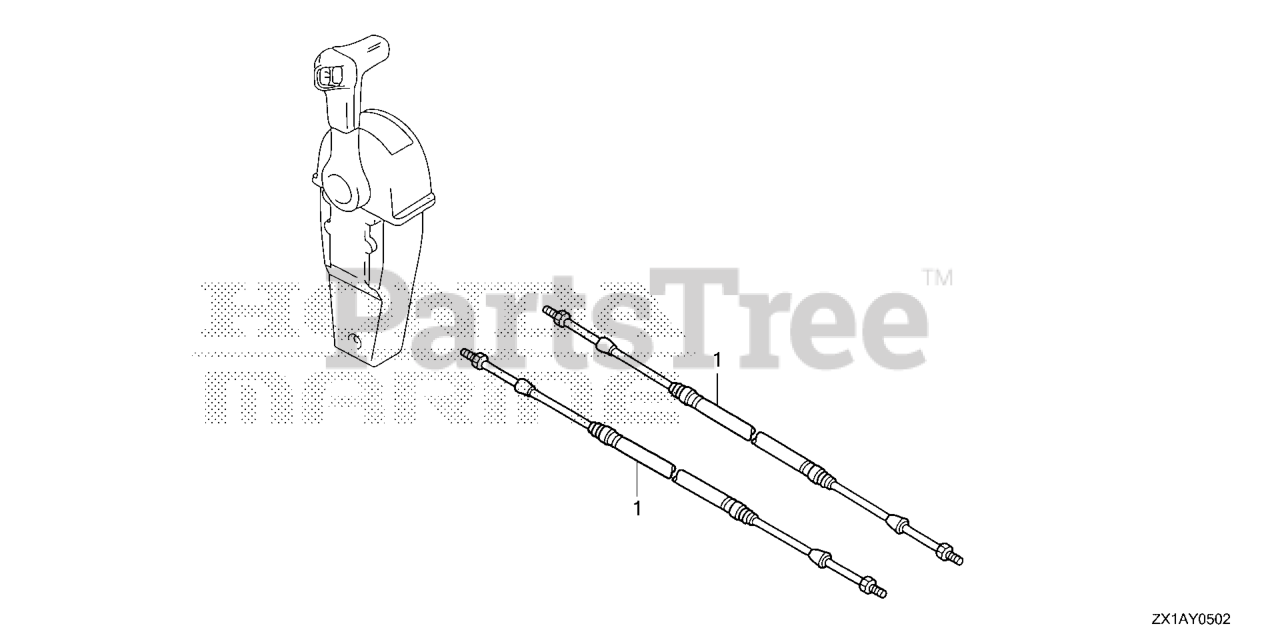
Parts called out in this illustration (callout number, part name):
1	CABLE ASSY., PUSH-PULL (33HPC-5FT)
1	CABLE ASSY., PUSH-PULL (33HPC-6FT)
1	CABLE ASSY., PUSH-PULL (33HPC-7FT)
1	CABLE ASSY., PUSH-PULL (33HPC-8FT)
1	CABLE ASSY., PUSH-PULL (33HPC-9FT)
1	CABLE ASSY., PUSH-PULL (33HPC-10FT)
1	CABLE ASSY., PUSH-PULL (33HPC-11FT)
1	CABLE ASSY., PUSH-PULL (33HPC-12FT)
1	CABLE ASSY., PUSH-PULL (33HPC-13FT)
1	CABLE ASSY., PUSH-PULL (33HPC-14FT)
1	CABLE ASSY., PUSH-PULL (33HPC-15FT)
1	CABLE ASSY., PUSH-PULL (33HPC-16FT)
1	CABLE ASSY., PUSH-PULL (33HPC-17FT)
1	CABLE ASSY., PUSH-PULL (33HPC-18FT)
1	CABLE ASSY., PUSH-PULL (33HPC-19FT)
1	CABLE ASSY., PUSH-PULL (33HPC-20FT)
1	CABLE ASSY., PUSH-PULL (33HPC-21FT)
1	CABLE ASSY., PUSH-PULL (33HPC-22FT)
1	CABLE ASSY., PUSH-PULL (33HPC-23FT)
1	CABLE ASSY., PUSH-PULL (33HPC-24FT)
1	CABLE ASSY., PUSH-PULL (33HPC-25FT)
1	CABLE ASSY., PUSH-PULL (33HPC-26FT)
1	CABLE ASSY., PUSH-PULL (33HPC-27FT)
1	CABLE ASSY., PUSH-PULL (33HPC-28FT)
1	CABLE ASSY., PUSH-PULL (33HPC-29FT)
1	CABLE ASSY., PUSH-PULL (33HPC-30FT)
1	CABLE ASSY., PUSH-PULL (33HPC-31FT)
1	CABLE ASSY., PUSH-PULL (33HPC-32FT)
1	CABLE ASSY., PUSH-PULL (33HPC-33FT)
1	CABLE ASSY., PUSH-PULL (33HPC-34FT)
1	CABLE ASSY., PUSH-PULL (33HPC-35FT)
1	CABLE ASSY., PUSH-PULL (33HPC-36FT)
1	CABLE ASSY., PUSH-PULL (33HPC-37FT)
1	CABLE ASSY., PUSH-PULL (33HPC-38FT)
1	CABLE ASSY., PUSH-PULL (33HPC-39FT)
1	CABLE ASSY., PUSH-PULL (33HPC-40FT)
